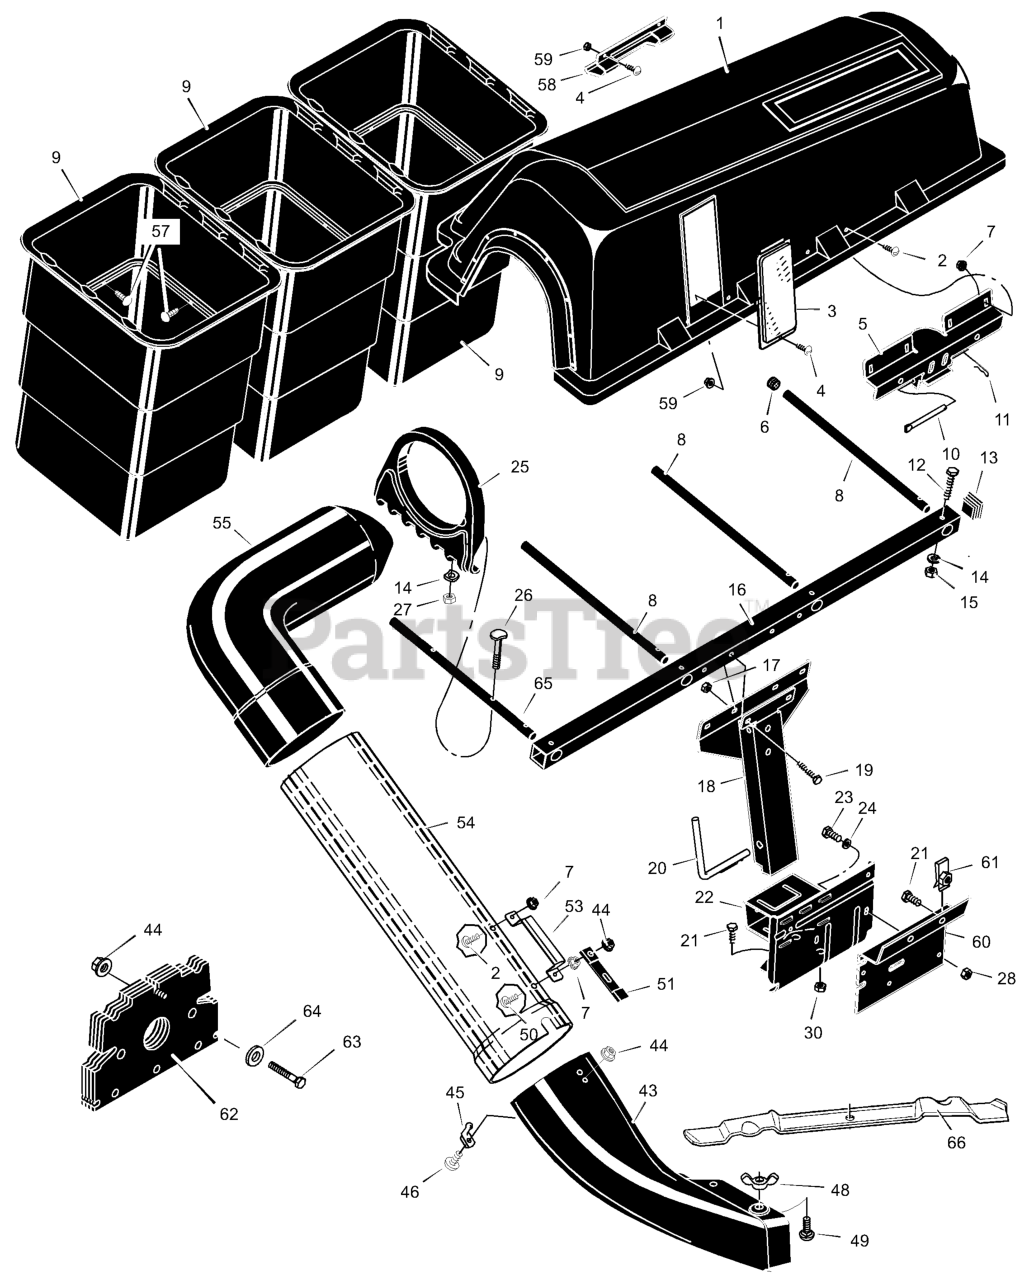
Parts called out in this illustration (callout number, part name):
1	Cover, Bagger
5	Hinge, Bracket
7	Nut, Hex
8	Tube, Container
9	Container
10	Pin, Cover Hinge
11	Pin, Hair
13	Plug
14	Lockwasher
16	Tube, Support
17	Nut
18	Assembly, Channel
20	Pin, Channel Mount
21	Bolt, Hex
22	Assembly, Bagger Mount
23	CAPSCREW, Hex Head, 5/16-18 x 1
25	Holder, Elbow
27	Washer
28	Nut, Super Flange
30	Nut, Hex
43	Tube, Extension
44	Locknut, Flange
45	Pin, Latch
46	Bolt, Carriage
48	Wingnut
49	Bolt, Carriage
51	Latch, Rubber
53	HANDLE, Connect Tube
54	Tube, Connecting
57	Fastener, Panel
58	Handle, Plastic
59	Nut, Hex
60	Bracket, Adapter
62	Weight, Front
65	Tube, Right Container
66	Blade, High Lift
